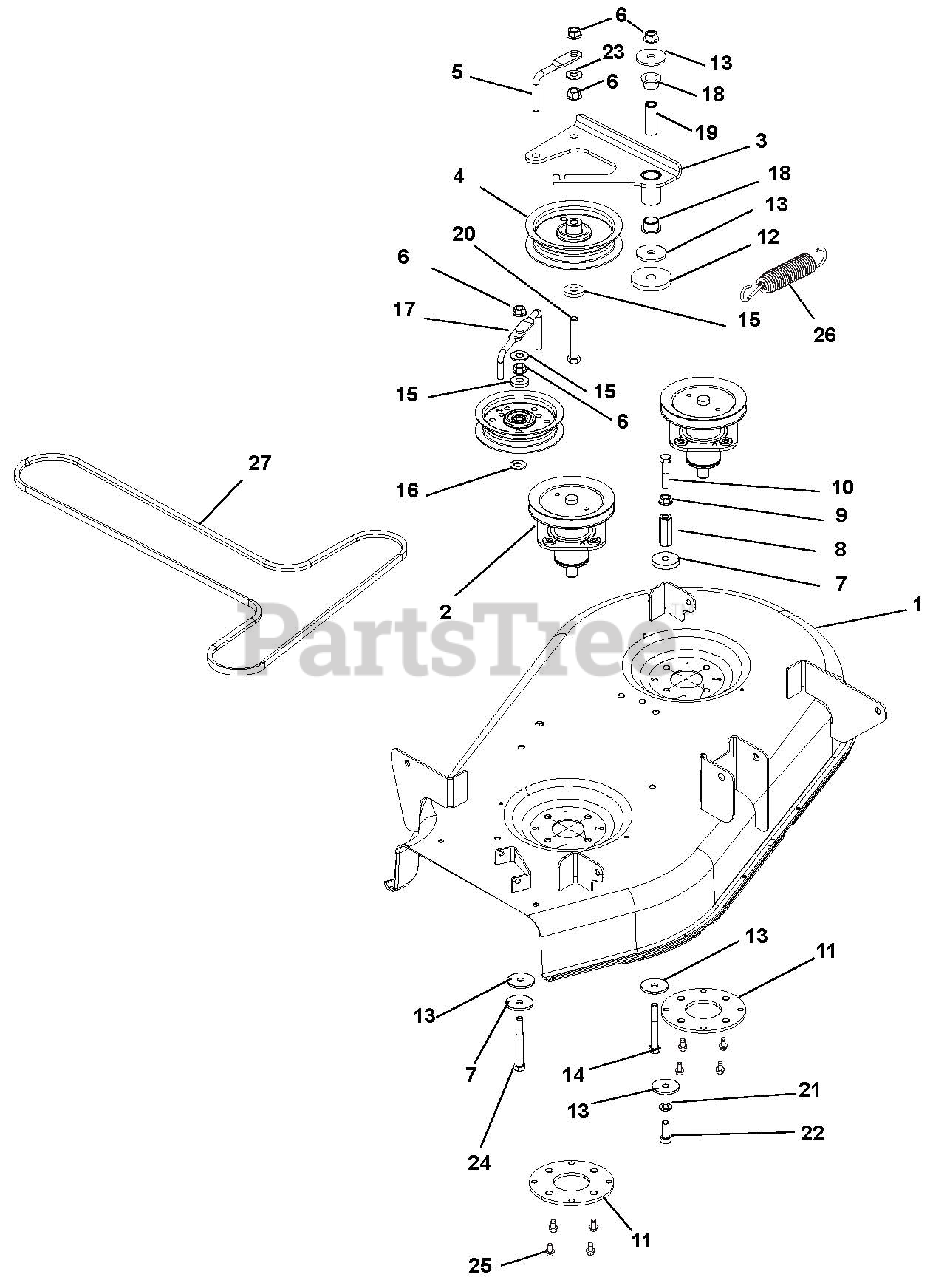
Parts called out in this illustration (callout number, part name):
1	KIT, 34" ARIENS DECK W/DECALS
2	KIT, DECK SPINDLE ASM (34/50)
3	IDLER ARM
4	ASM, IDLER 4"
5	WIREFORM, BELT FINGER
6	@NUT-LK-TOP-FLG .38-16 YWZC
7	WSHR,FLT STL.406X1.50X.245YWZC
8	NUT COUPLING .375-16X1.75
9	@NUT-SPNLK-FLG .375-16 YWZC
10	@BLT-HEX .38-16X1.75 GR5 YWZC
11	PLATE-REINF, SPINDLE
12	WSHR-FL-STL .469X2.00X.25 YWZC
13	WSHR-FL-STL .380X1.50X.125YWZC
14	@BLT-HEX .38-16X3.00 GR5 YWZC
15	WSHR-FL-STL .406X1.00X.188 YWZ
16	@WSHR-FL-STL.438X1.00X.083 YWZ
17	WIREFORM, BELT FINGER
18	BSHG-FLG, .625X.750X.500X1.00
19	SPACER, .375IDX.625ODX1.66 PM
20	@BLT-HEX .38-16X2.25 GR5 YWZC
21	@WSHR-LK .38X.094 REG YWZC
22	@BLT-HEX .38-16X1.00 GR5 YWZC
23	@WSHR-FL-STL.406X.812X.065 YWZ
24	@BLT-HEX .38-16X2.75 GR5 YWZC
25	@SCR-TAP .38-16X.75 HWH TR YWZ
26	SG-TENS .135X.98X6.0 WLD 62
27	V-BELT, HA-WRAPPED
